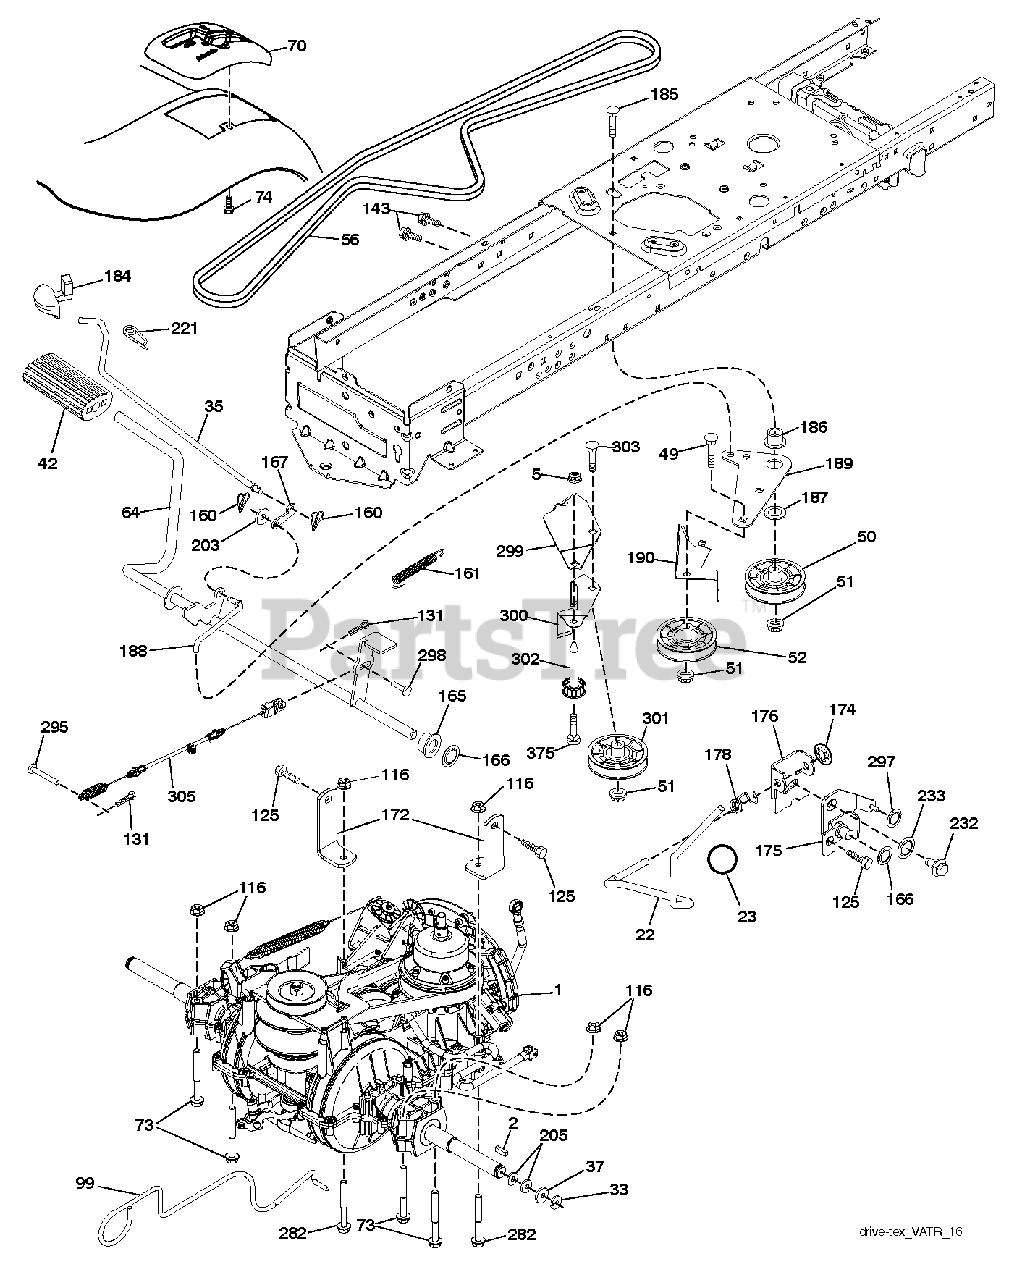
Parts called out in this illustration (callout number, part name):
2	SQUARE KEY
5	LOCKNUT
22	ROD.SHIFT.LT.TEX.VARIATOR
23	KNOB.DELUXE.(PISTOL.GRIP).BLAC
33	E-RING LT
35	ROD.BRAKE.PARKING.LT.T
49	BOLT
50	IDLER.FLAT.910.OFFSET
51	NUT LOCK FLG 3/8-16 UNC
52	IDLER.V-GROOVE.910.OFFSET
56	BELT.DRIVE.MOWER.TEX.42"
64	SHAFT.ASM.PEDAL.BRAKE.
70	CONSOLE.AUTO.VARIATOR.BLACK
73	BOLT HEX 5/16-18 GR 5
74	SCREW.HI-LO.CONSOLE
99	ROD.BYPASS.VARIATOR
116	NUT LOCK HEX FLANGE 5/16-18
125	SCREW
143	SCREW LT
160	RETAINER CLIP
161	SPRING, RETURN LT
165	BUSHING.SHAFT.BRAKE.HAND
166	NUT.PUSH.625
167	LATCH.BRAKE.SPRING
172	STRAP.TORQUE.VARIATOR
174	NUT.PUSH.500.2006
175	SHAFT.ASM.SHFT.T2.TLT
176	ARM.CLEVIS.ROD.SHIFT
178	SPRING.SHIFT.GT2006
184	HANDLE.PARKING.BRAKE.LTTEX.667
186	SPACER.RETAINER
187	WASHER 12/32X2X10GA
188	LINK.CLUTCH.GROUND.DRIVE
189	BELLCRANK.GROUND.DRIVE.TEX.
190	KEEPER.BELLCRANK.DRIVE
203	WASHER
221	RETAINER.SPRING.CLIP.H
232	BOLT FIN HEX 7/16-14 X 1
233	WASHER SERRATED
282	BOLT HEX FLGHD 5/16-18X3 GR. 5
295	PIN.CLEVIS.183
297	PIN.CLEVIS.CBL.BRK.VARIATOR.TX
298	PIN.CLEVIS.CBL.BRK.VARIATOR.TX
299	BRACKET.MOUNT.IDLERS
300	PULLEY.IDLER.V-GROOVE
301	PULLEY.IDLER.V-GROOVE
302	RB PULLEY.IDLER.FLAT.2.0"OD RP
303	BOLT CARRIAGE
305	CABLE.BRAKE.VARIATOR.TEX
